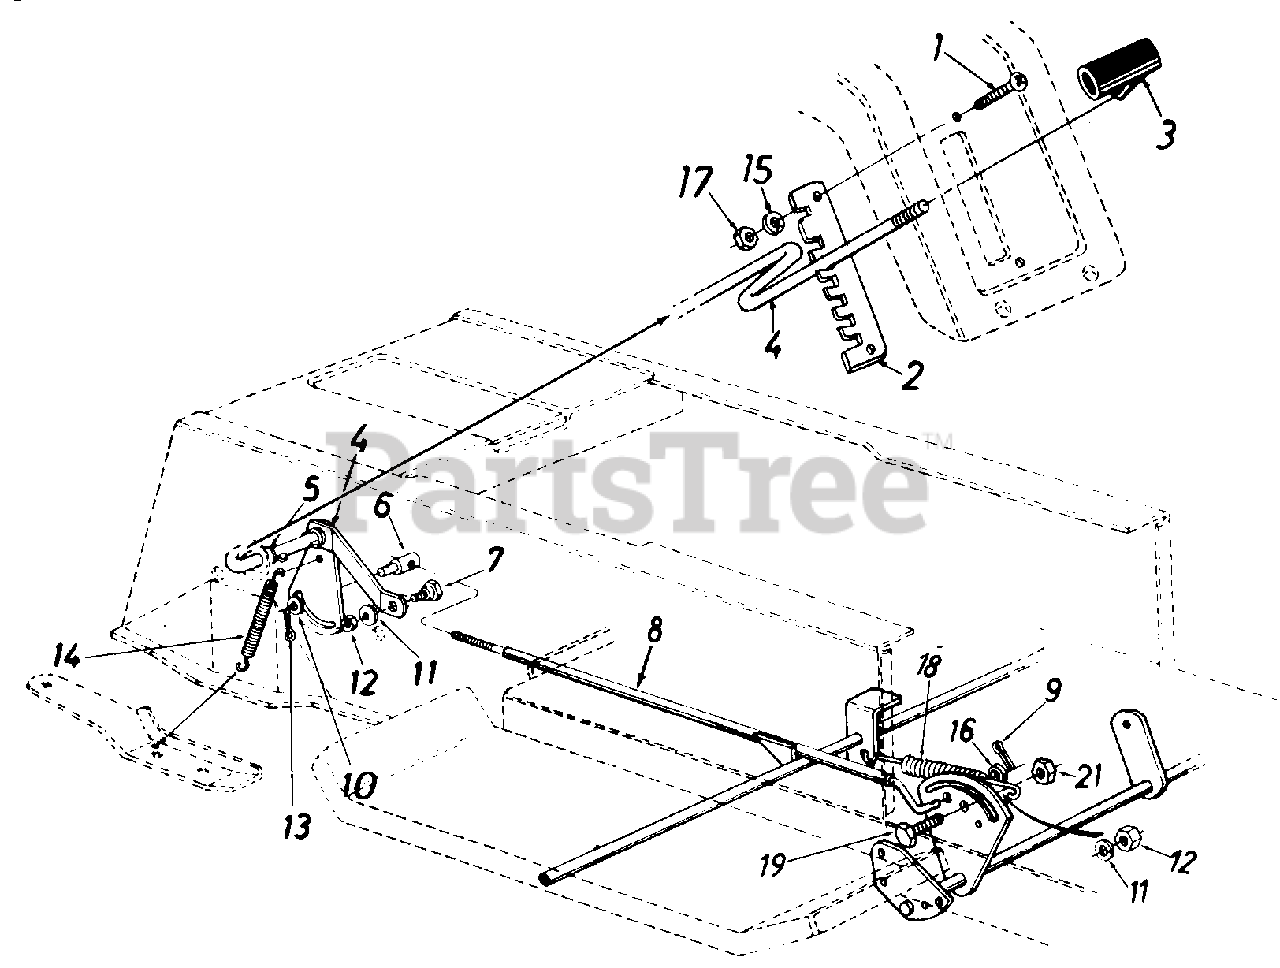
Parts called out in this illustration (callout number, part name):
1	Truss Mach. Scr. 1/4-20 x .62" Lg.
2	Speed Selector Plate
3	Shift Knob
4	Speed Selector Cam Ass'y.
5	Flat Washer .53" I.D. x .93"
6	Ferrule 3/8-24 x .37" Dia.
7	Shoulder Bolt .435" Dia. x .160
8	Speed Control Rod Ass'y.
9	Cotter Pin 3/32" Dia. x .75"
10	Fl-Wash. .385" I.D. x .62" O.D.
11	L-Wash. 5/16" I.D.
12	Hex Nut 5/16-18 Thd.
13	Cotter Pin 3/32 Dia. x .75"
14	Spring
15	L-Wash. 1/4" I.D.
16	Fl-Wash. .47" I.D. x .88" O.D.
17	Hex Nut 1/4-20 Thd.
18	Ext. Spring 4.75" Lg.
19	Hex Cap Bolt 5/16-18 x 1" Lg. (Grade 5)
21	Hex L-Nut 5/16-18 Thd.
